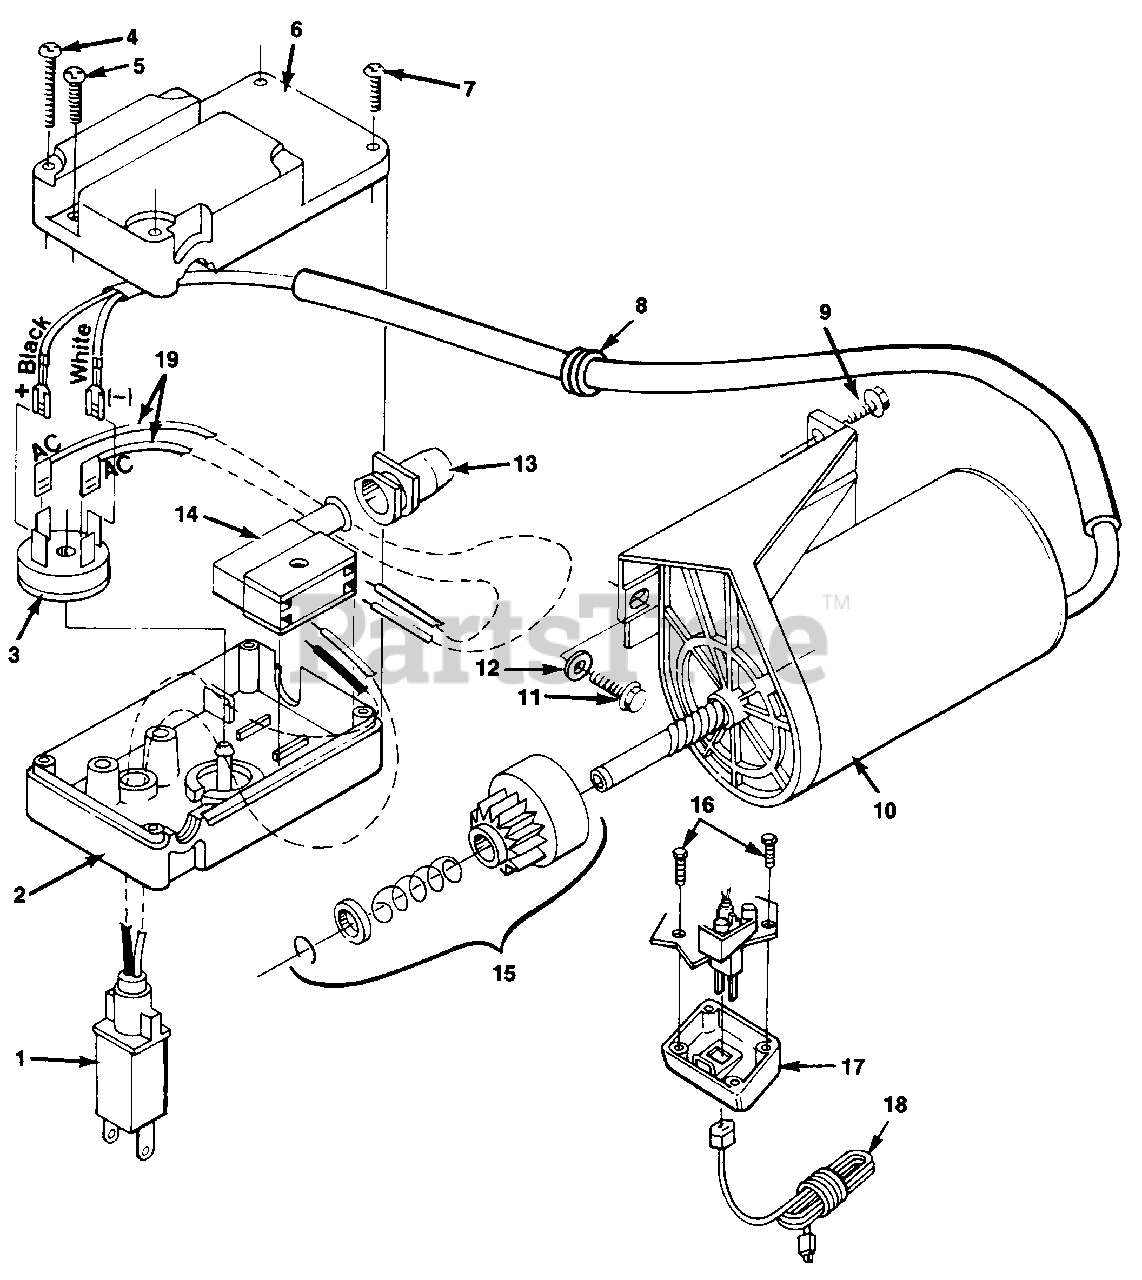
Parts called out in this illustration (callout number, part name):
1	PLUG-Electrical
2	HOUSING-Electrical start
3	RECTIFIER
4	SCREW-Thd. forming #8-16 x 1 1/4"
5	SCREW-Thd. forming
6	COVER-Electric start
7	SCREW-Thd. forming #8 x 1/2"
8	GROMMET
9	SCREW-Thd. forming
10	MOTOR- Pinion end plate
11	SCREW-Thd. forming 12-24 x 5/8"
13	BOOT-Switch
14	SWITCH-Electric starter
16	SCREW #10 x 3/4"
17	COVER-Starter
19	LEAD- Electrical
